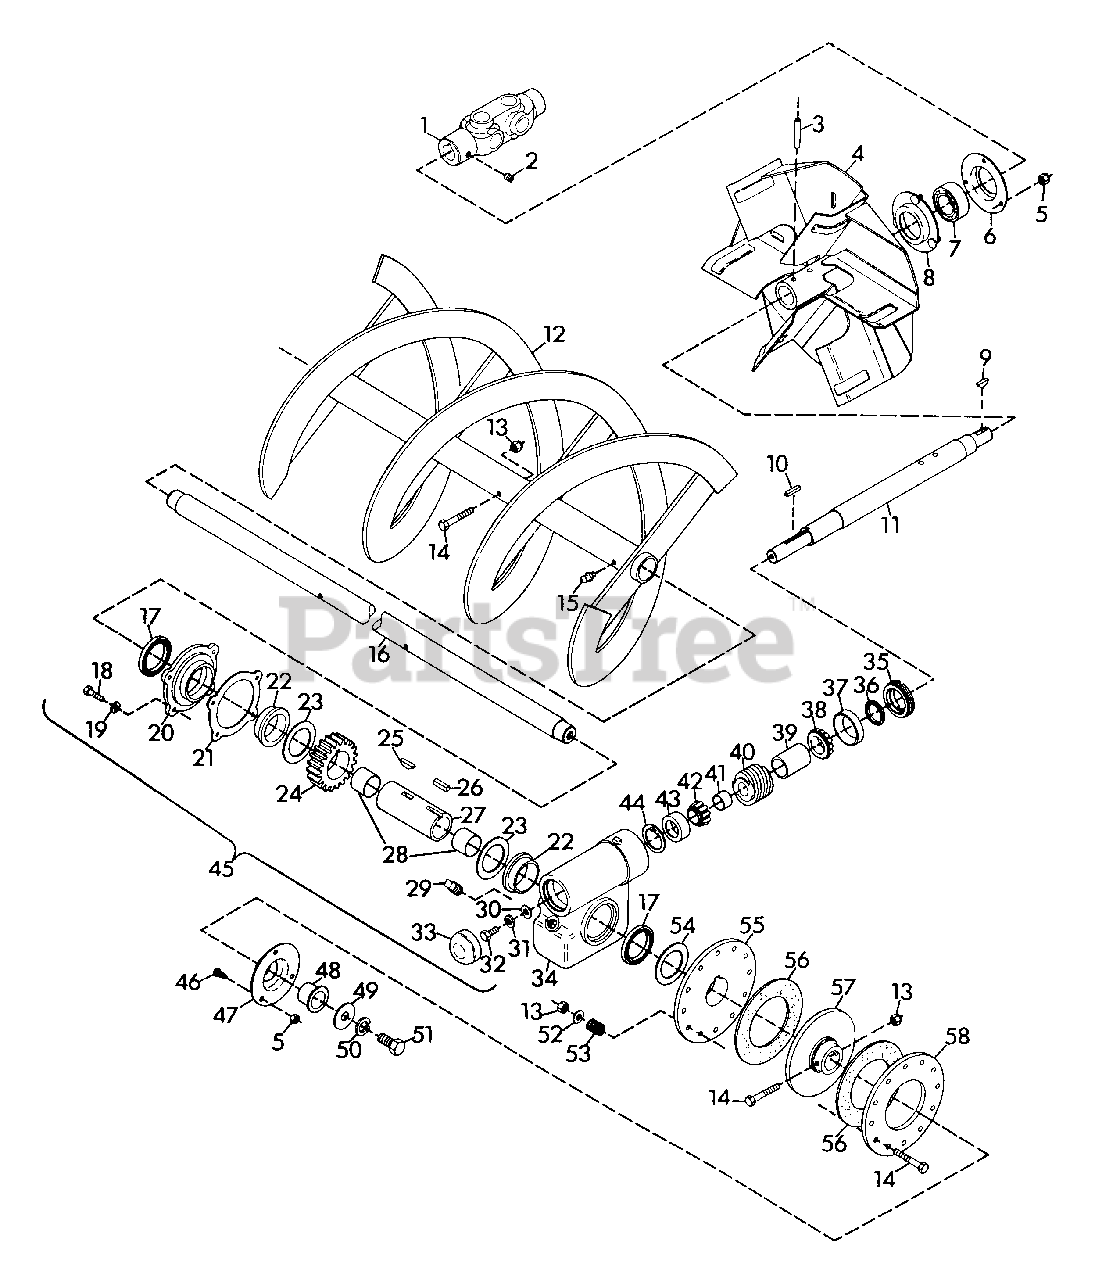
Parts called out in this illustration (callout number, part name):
1	ASSEMBLY, U-JOINT
2	SCREW, SET 3/8-16X.375
3	PIN, ROLL 5/16X1.75
4	FAN
5	NUT, LOCK 1/4-20
6	BEARING, FLANGE
7	BEARING, BALL
8	BEARING, FLANGE
9	KEY, WOODRUFF 3/16X7/8 HRD #11
10	KEY, STRAIGHT SAE 1035
11	WORM SHAFT
12	RAKE, RIGHT 32"
12	RAKE, LEFT 32"
13	NUT, LOCK 5/16-18
14	BOLT, HEX 5/16-18X2.00
15	FITTING, LUBE 1/4-28
16	SHAFT, 32" RAKE
17	SEAL
18	BOLT, HEX 1/4-20X.875
19	WASHER, LOCK 1/4 EXT TH TYA
20	COVER, GEARCASE
21	GASKET
22	BUSHING, FLANGE 1.62X1.87X11
23	WASHER, 1.625X2.50X.012
24	GEAR, WORM
25	KEY, FEATHER
26	KEY, STRAIGHT
27	GEARCASE SHAFT
28	BUSHING, SLEEVE
29	PIPE PLUG
30	WASHER, FLAT .344X.688X.065
31	WASHER, LOCK 5/16 SP
32	BOLT, HEX 5/16-18X.75
33	CAP, DUST
34	GEARCASE
35	ADJUSTMENT PLUG
36	SEAL
37	BEARING CUP
38	BEARING CONE
39	BEARING SPACER
40	WORM
41	SPACER, BEARING
42	BEARING CONE
43	BEARING CUP
44	RING, SNAP INTERNAL 1.781
45	GEARCASE ASSEMBLY
46	BOLT, RIB NECK 1/4-20X.5
47	SUPPORT, BEARING
48	BUSHING, FLANGE 1X1.12X.625
49	WASHER, FLAT .515X1.441X.1
50	WASHER, LOCK 1/2 SP HEAVY
51	BOLT, HEX 1/2-13X1
52	WASHER, FLAT
53	SPRING, COMPRESSION
54	WASHER
55	DRIVER
56	FRICTION DISC
57	DRIVEN PLATE
58	PRESSURE PLATE
